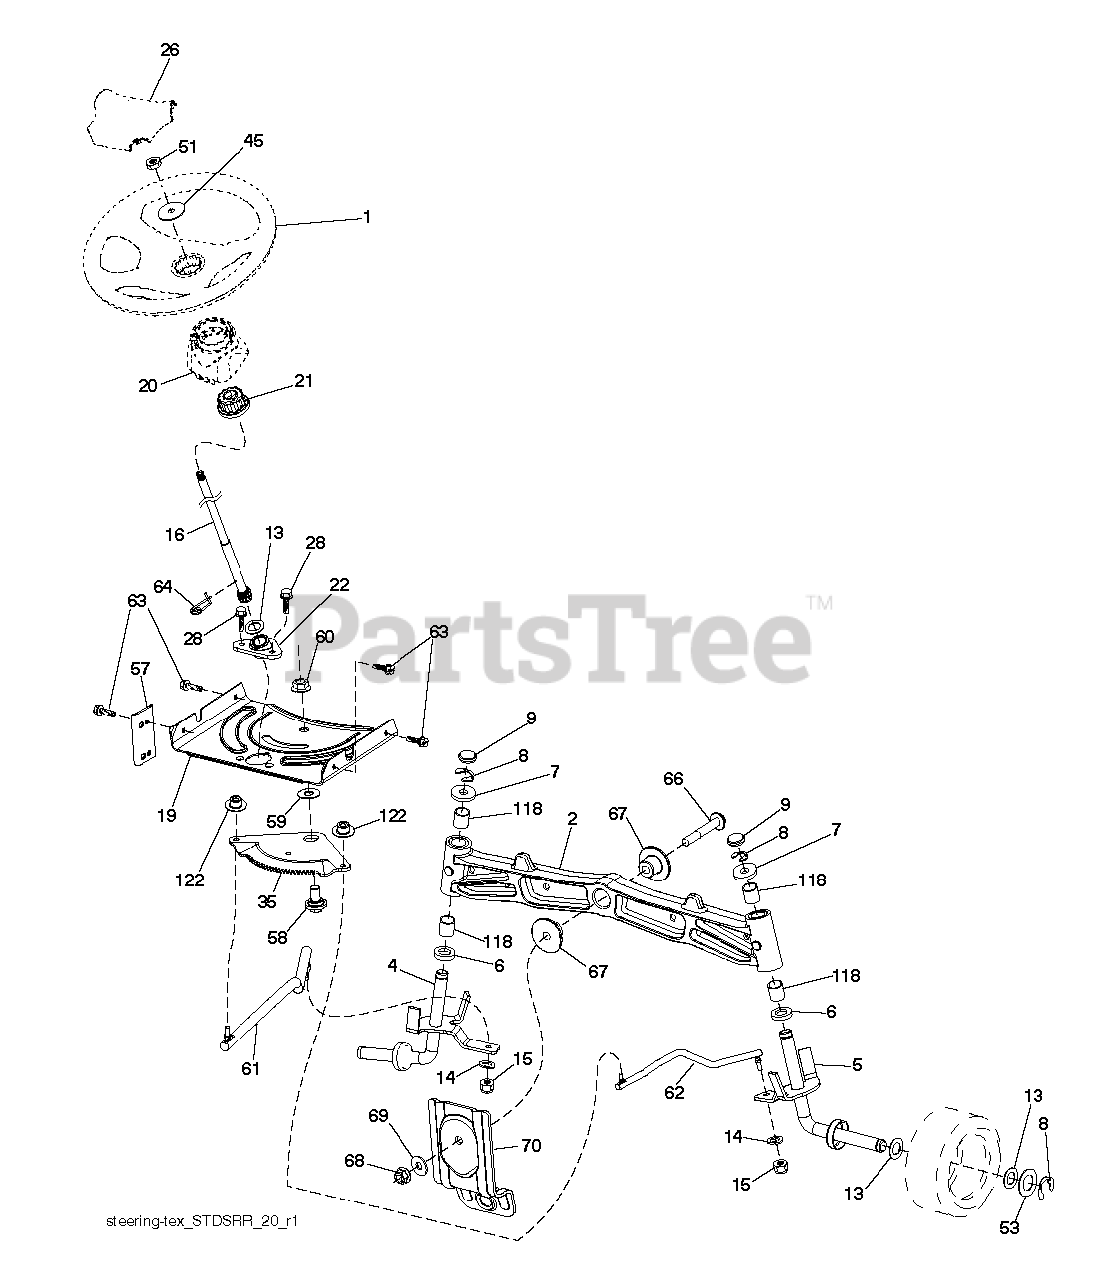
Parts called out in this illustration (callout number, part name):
1	WHEEL.STEERING.STDSRR.BLK/OV
2	AXLE.SVC.ASM CAST IRON.TEX
4	SPINDLE.WELDED.LH.15"TEX
5	SPINDLE.WELDED.RH.15"T
8	RING CLIP
9	CAP.SPINDLE
14	WASHER, LOCK 3/8
15	NUT CROWNLOCK 3/8-24
16	SHAFT.STEER.STEALTH.DD
19	PLATE.STEER.DDL.NLT/NG
21	ADAPTER, WHEEL STNG..
22	STEERING.SUPT.LOWER.
26	CAP.WHL.STRNG.STDSRRD.SRS.BLK
28	SCREW, 3/8-16X3/4
35	GEAR.SECTOR.PLATE.DDL.
45	WASHER 9/16"ID, 2 3/8"OD
51	NUT.HEX.1/2-20
53	WASHER.HARDENED
57	BRACKET.UPSTOP.TEX
58	BOLT.SHOULDER.SECTOR.P
59	WASHER.THURST.SECTOR.S
60	NUT FLANGE LOCK 5/8-11
61	DRAGLINK.LH.BALLSTUD.D
62	DRAGLINK.RH.BALLSTUD.D
63	SCREW
64	RETAINER.CLIP.SPRING.S
66	BOLT HEX FGHD 7/16-14 X 3 SERR
67	BUSHING.PM.FRONT AXLE
68	NUT.LOCK.FLANGE.7/16
69	WASHER.1.5X.505X.118
70	BRKT.DECK.SUSPENSION.F
118	BUSHING, AXLE CAST
